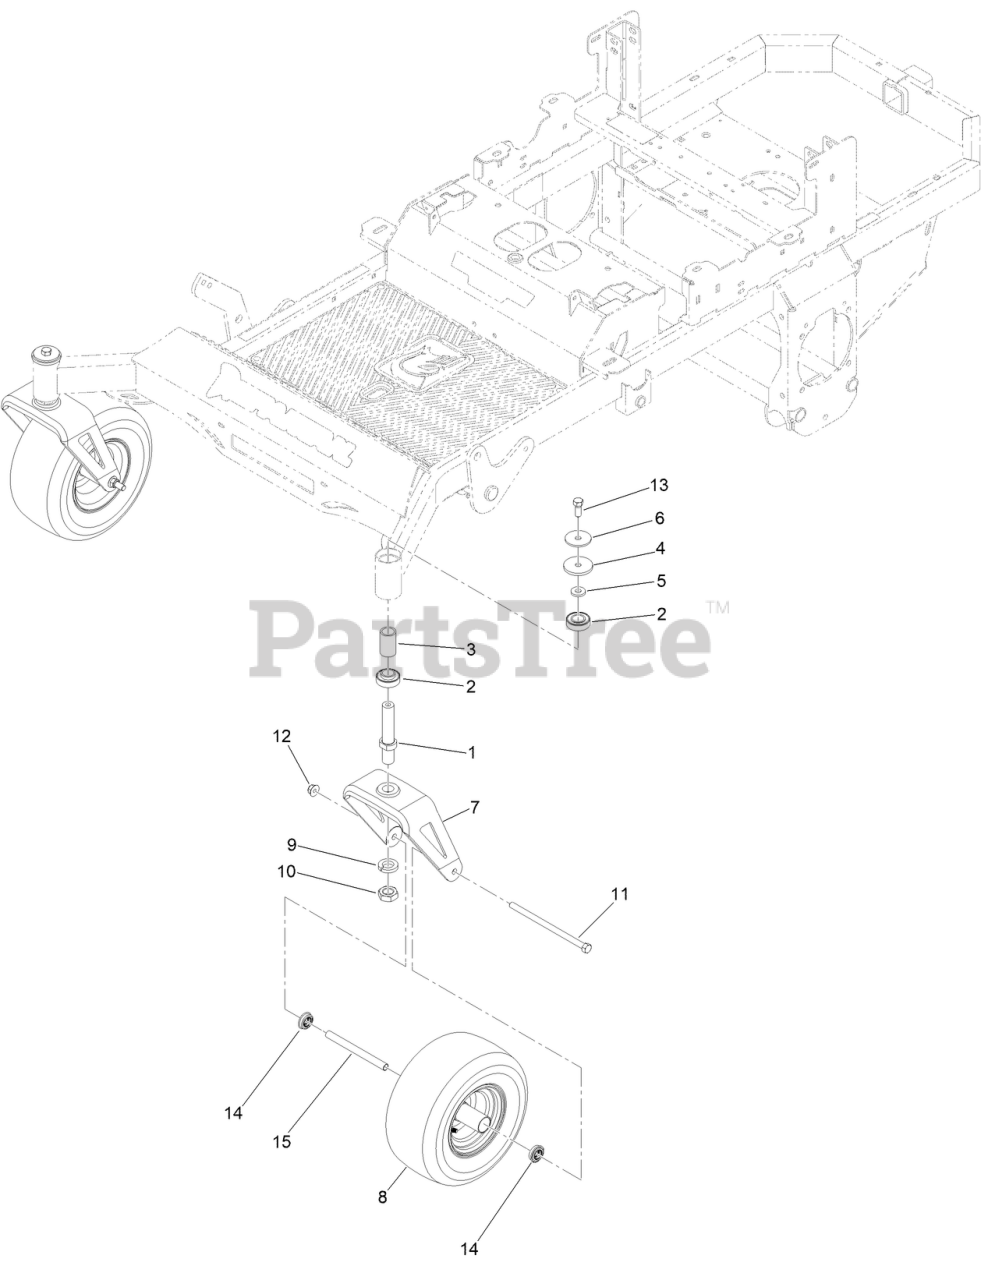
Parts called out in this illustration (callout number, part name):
1	MWR CASTER SHAFT
2	BEARING-BALL
3	CASTER FORK SHAFT BEARING SPACER
4	1/2 FENDER WASHER 1-1/4IN OD ZINC
5	FT HUB PLASTIC WASHER
6	MWR CASTER SHAFT WASHER
7	RT AND SRT CASTER WHEEL FORK
8	RZ/RT PRO FT TIRE ASSY-SMOOTH TREAD
9	1IN L/W MED SPLIT ZC
11	SCREW-HH
12	NUT-LOCK
13	1/2-20 X 1-1/4 HEX FLANGE BOLT GR 8 YZ
14	RZ FT WHEEL BEARING
15	MWR FT WHEEL SPANNER
